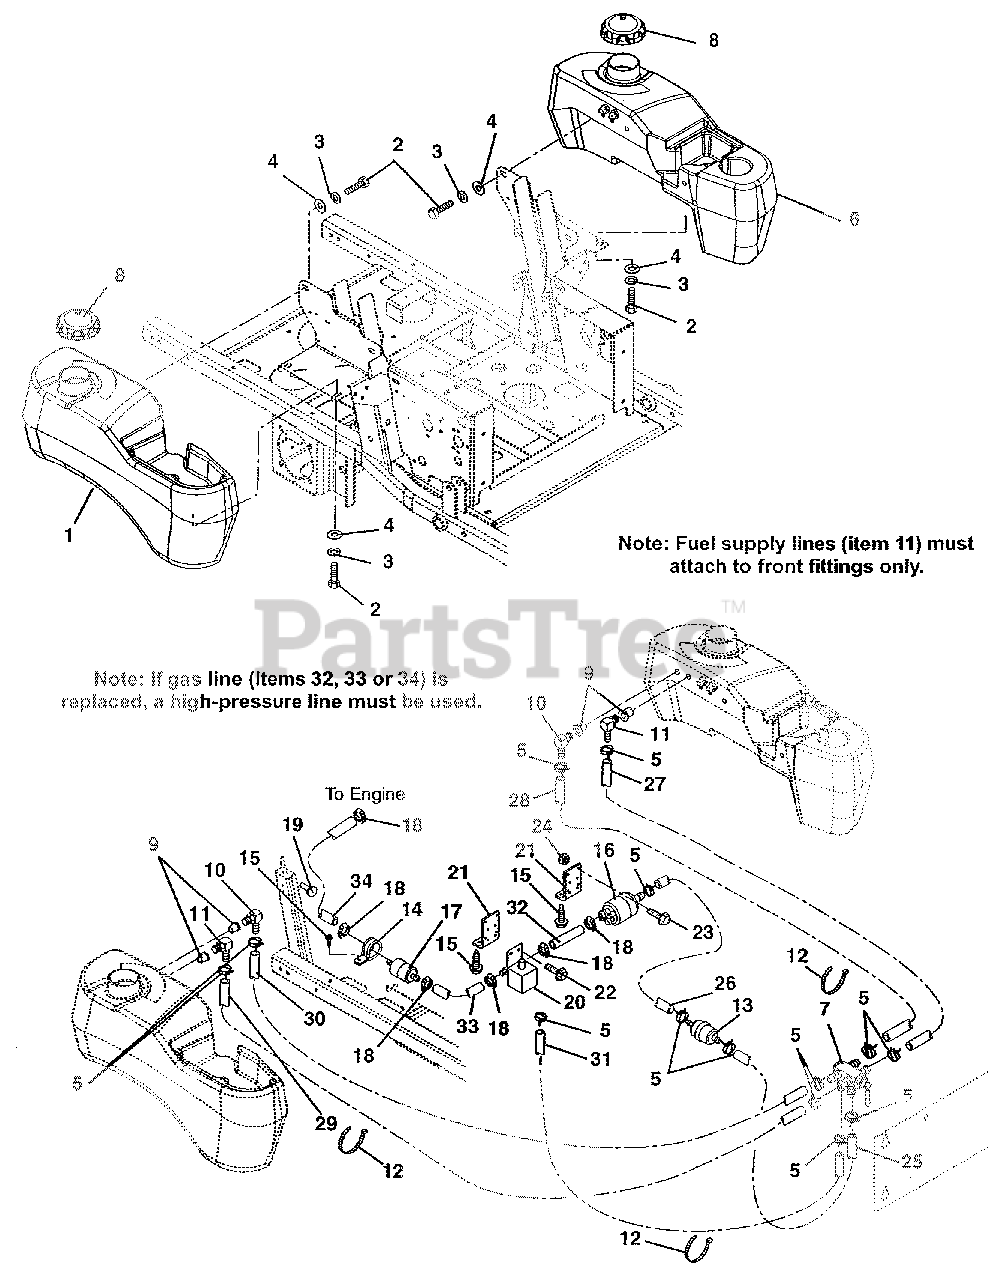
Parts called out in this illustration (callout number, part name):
1	Fuel Tank, Right Hand
2	Bolt, Hex .31-18 x .75 Grade 5
3	Washer, Locking .31 x .078
4	Washer, Flat Steel .38 x .875 x .083
5	Hose, Clamp
6	Tank, Left Hand Fuel (EYE-Q)-200 Series-EFI
7	Valve, Fuel
8	Cap, Gas
10	Fitting, Tank Elbow
11	Fitting, Tank Elbow
12	Tie, Cable
13	Filter, Fuel .31
14	Clamp, 2.18
15	Screw, Tapping .38-16 x .50 Hex Washer Head
16	Pump, EFI Fuel
17	Filter, Fuel
18	Hose Clamp
19	Tube Clip .75
20	Regulator, EFI Fuel
21	Bracket, Pump and Regular Mounting
22	Screw, Tapping .25-20 x .37 Hex Washer Head
23	Screw, Machine 10-24 x .50 Hex Washer Head
24	Nut, Locking Top 10-24
25	Hose, .31 ID Low Pressure
26	Hose, .31 ID Low Pressure
27	Hose, .31 ID Low Pressure Left Hand
28	Hose, .31 ID Low Pressure Left Hand
29	Hose, .31 ID Low Pressure Right Hand
30	Hose, .31 ID Low Pressure Right Hand
31	Hose, .31 ID Low Pressure
32	Gas Line .31 ID Hight Pressure
33	Gas Line .31 ID Hight Pressure
34	Gas Line .31 ID Hight Pressure
